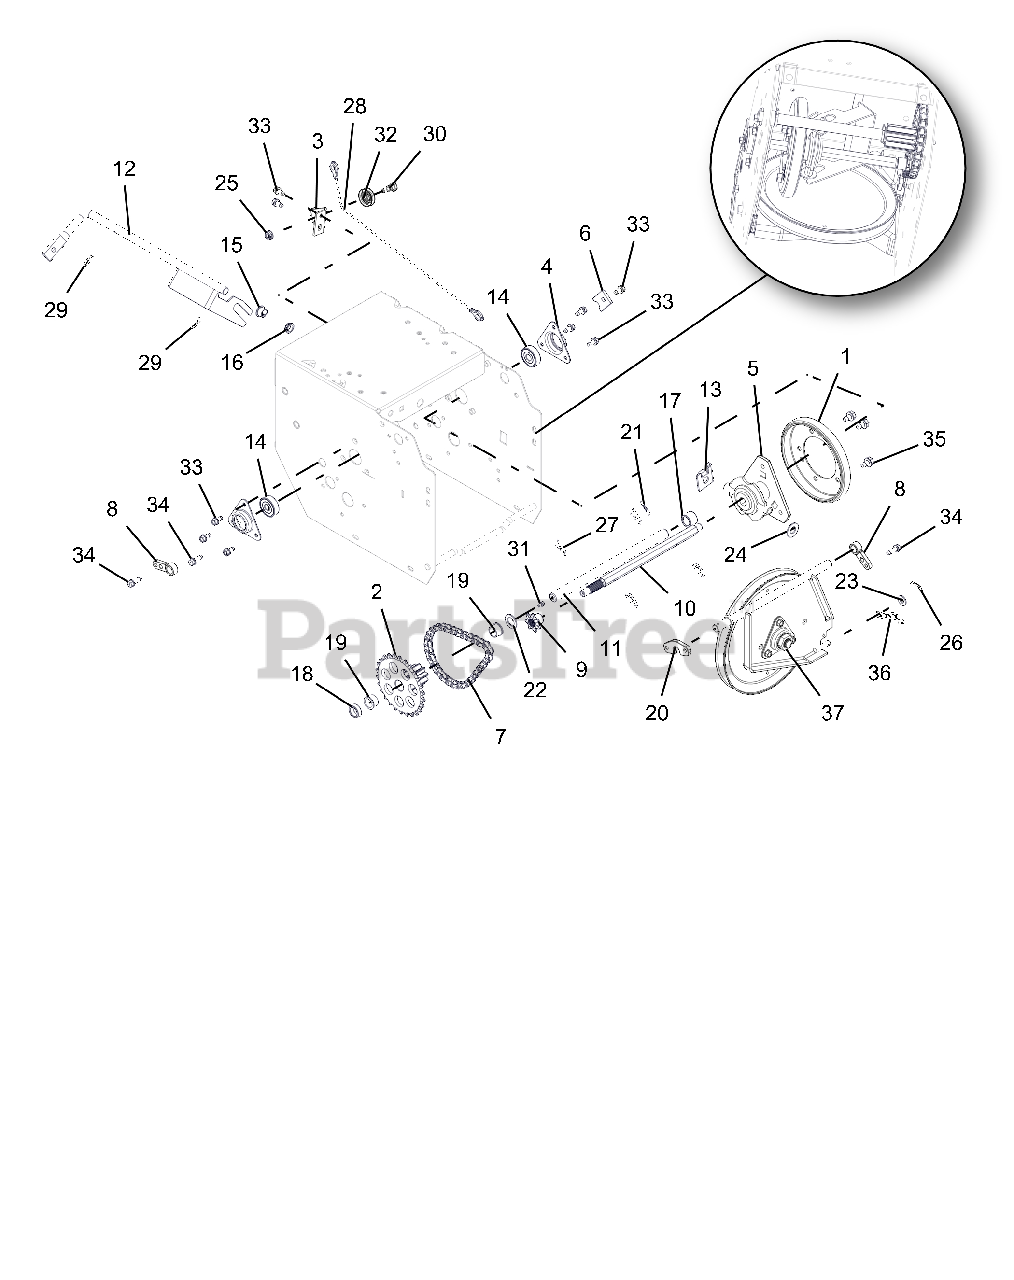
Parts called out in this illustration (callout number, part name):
1	FRICTION, DISC
2	PINION & SPROCKET
3	BRACKET, CABLE PULLEY
4	FLANGE, BEARING
5	CARRIER, DRIVE DISK
6	TAB, ANTI ROTATION
7	CHAIN - #41, 32 PITCHES
8	SUPPORT BUSHING, SWING GATE
9	SPROCKET, PINION 7T W/SPLINE
10	SHAFT, HEX W/SPLINE TRACK
11	SHAFT, PINION TRACK
12	WELDMENT, SHIFT FORK
13	BRACKET, FORMED - SHIFT FORK
14	BRG-BALL .437X1.375X.437
15	BUSHING, POLYLINER-.50 SPLIT
16	BUSHING, POLYLINER-.50 SNAPIN
17	SPACER, .635X.880X.611
18	BSHG-SLV, .635X.880X.305
19	BSHG-FLG .625X.750X.500X.875
20	SPACER, SWING GATE
21	@PIN-GRV .125X1.00 TP E ALLOY
22	WSHR-FL-STL .630X1.005X.062 YZ
23	@WSHR-FL-STL.344X.688X.065YWZC
24	WSHR-FL-STL .505X1.00X.062YWZC
25	@NUT-LK-CTR-FLG .25-20 YWZC
26	PIN-HAIR INT .08X.18X1.18 YWZC
27	PIN, SPRING CLIP
28	CABLE, LOWER TRACTION (CMPCT)
29	CLIP, SPRING
30	BOLT, SHLDR-.375X.375X.25-20
31	ZERK,FITTING .25X.125 DRIVE IN
32	PULLEY, CABLE
33	SCR-TAP .25-20X.50 HWH TR YWZ
34	SCR-TAP-PM .25-20X.75 TR YWZ
35	@SCR-TAP .31-18X.50 HWH TR YWZ
36	SPRING, EXT. .043X.438X1.64
37	PLATE, SWING - ASSEMBLY
